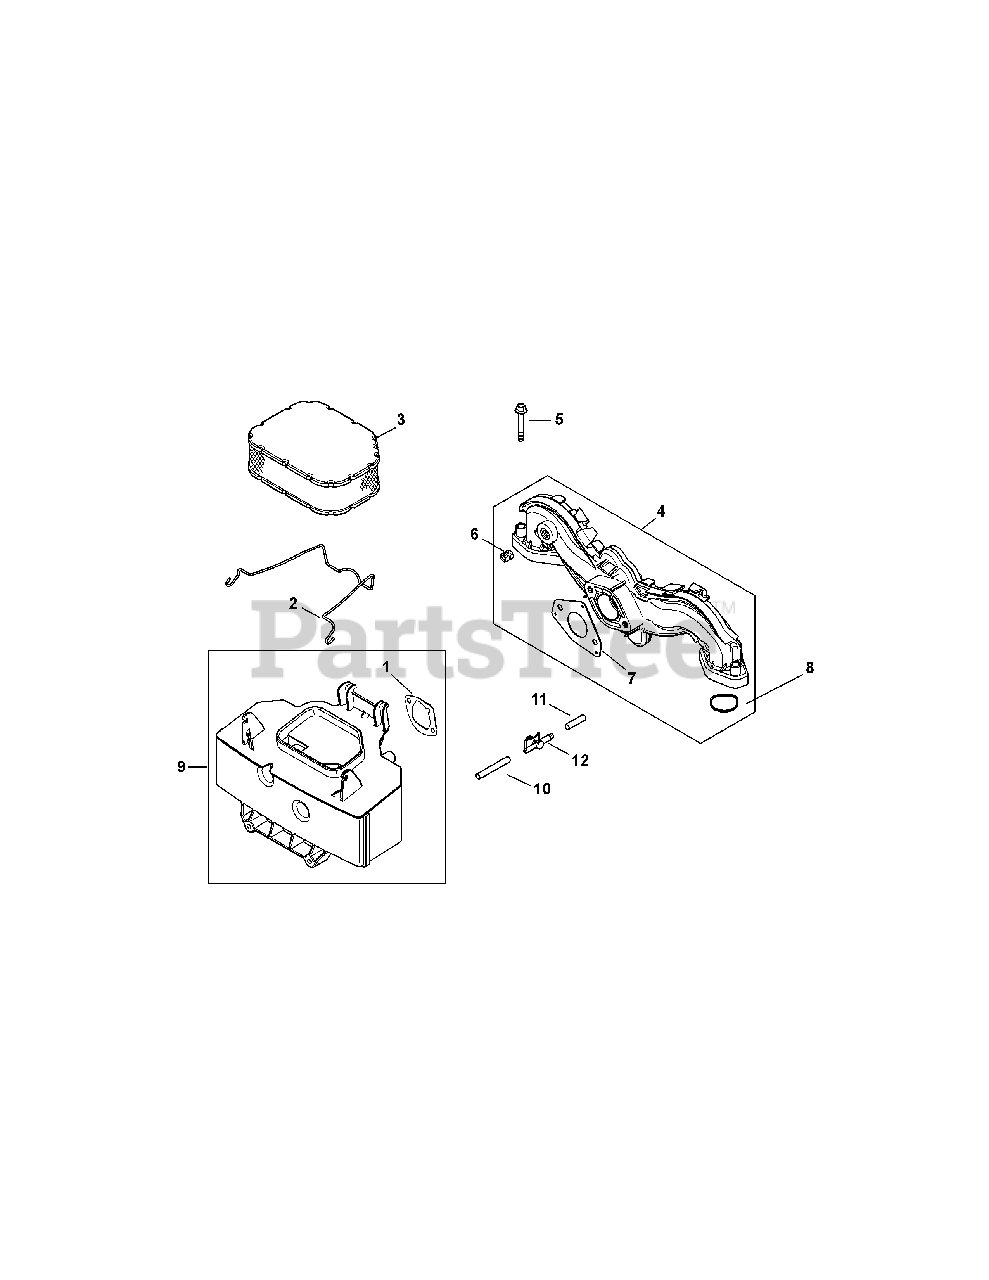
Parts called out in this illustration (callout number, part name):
1	Air Cleaner Base Gasket
2	Air Cleaner Element Latch
3	Air Filter Element
4	Intake Manifold Kit
5	Screw, M6 x 1.0 x 40
6	Pipe Plug, 1/8
7	Carburetor Gasket
8	O-Ring, Intake Port
9	Air Cleaner Base
10	Evaporative Hose, 20"
12	Evaporative Connector
